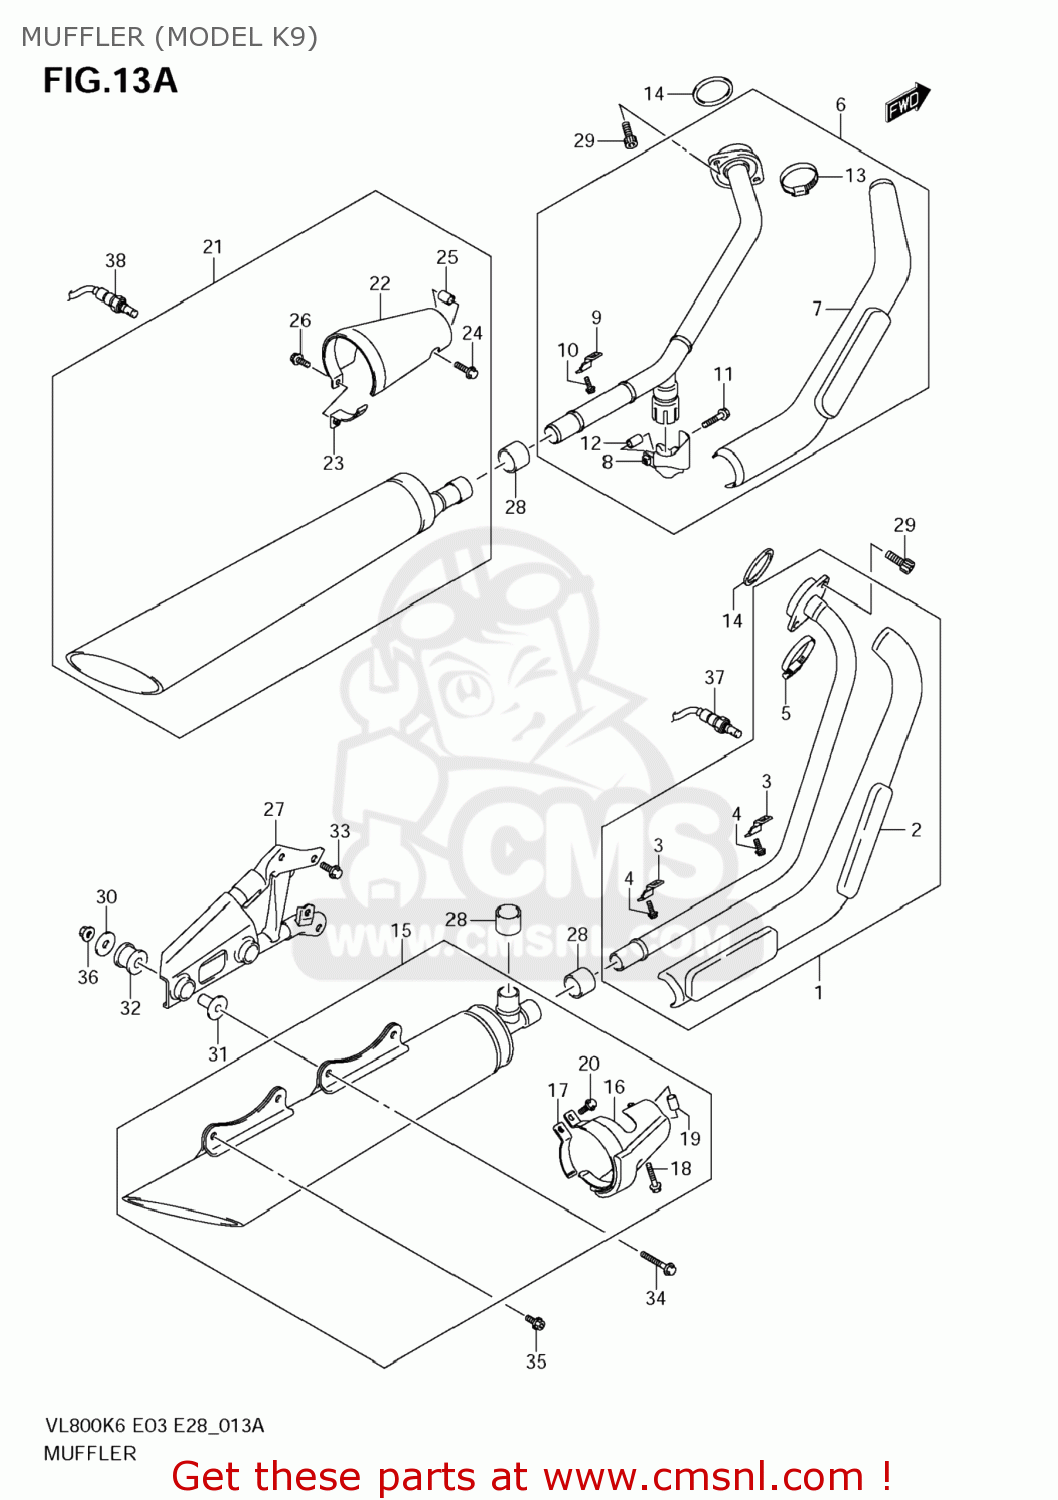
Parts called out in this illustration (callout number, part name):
1	PIPE,EXHAUST FR
2	COVER
3	CLAMP,EXHAUST COVERER
4	BOLT
5	BAND
6	PIPE,EXHAUST RR
7	COVER
8	CLAMP
9	CLAMP,EXHAUST COVERER
10	BOLT
11	BOLT(8X35)
12	SPACER
13	BAND
14	GASKET,EXHAUST PIPE (NAS)
15	BODY,MUFFLER FR
16	COVER
17	CLAMP
18	BOLT(8X35)
19	SPACER
20	BOLT
21	BODY,MUFFLER RR
22	COVER
23	CLAMP
24	BOLT(8X35)
25	SPACER
26	BOLT
27	BRACKET,MUFFLER SUPPORT
28	CONNECTOR,MUFFLER
29	BOLT(8X25)
30	WASHER(8.5X33X1.5)
31	SPACER(8.6X12X27.1)
32	CUSHION
33	BOLT(8X16)
34	BOLT
35	BOLT(8X20)
36	NUT
37	SENSOR,OXYGEN
38	SENSOR,OXYGEN
